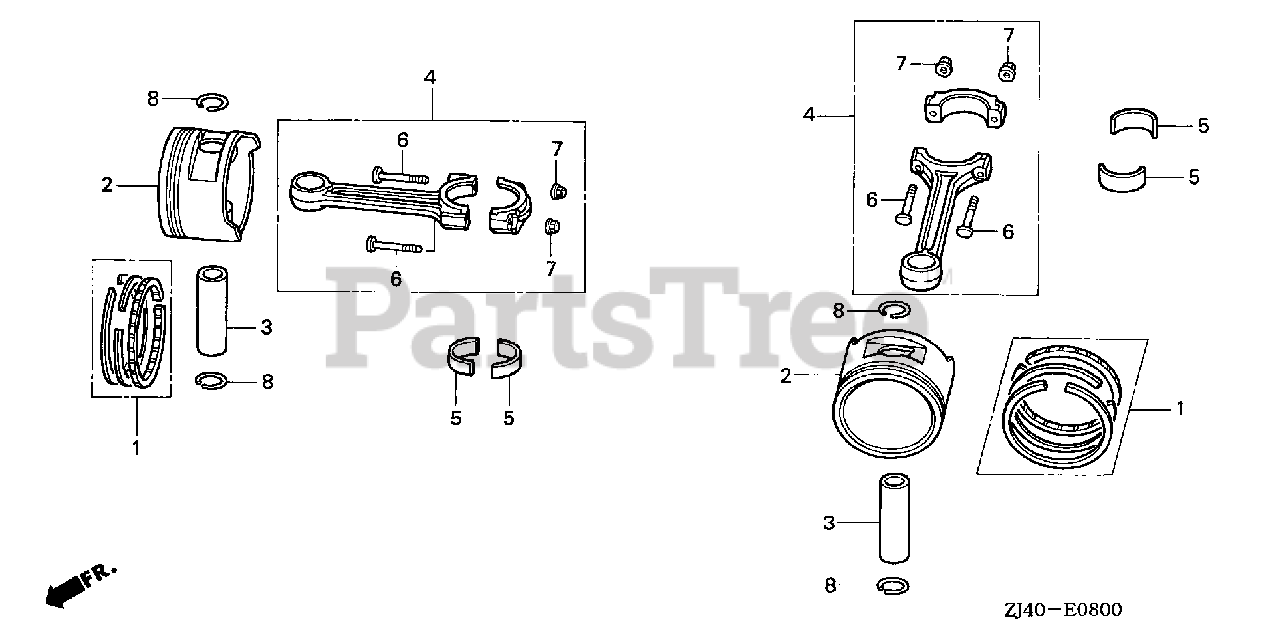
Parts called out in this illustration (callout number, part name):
1	RING SET, PISTON (STD) (NIPPON)
1	RING SET, PISTON (0.25)
1	RING SET, PISTON (0.50)
1	RING SET, PISTON (0.75)
2	PISTON (STD)
2	PISTON (0.25)
2	PISTON (0.50)
2	PISTON (0.75)
3	PIN, PISTON
4	ROD SET, CONNECTING
5	BEARING A, CONNECTING ROD (BLUE)
5	BEARING B, CONNECTING ROD (BLACK)
5	BEARING C, CONNECTING ROD (BROWN)
5	BEARING D, CONNECTING ROD (GREEN)
5	BEARING E, CONNECTING ROD (YELLOW)
5	BEARING F, CONNECTING ROD (PINK)
5	BEARING G, CONNECTING ROD (RED)
6	BOLT, CONNECTING ROD
7	NUT, CONNECTING ROD
8	CLIP, PISTON PIN (18MM)
